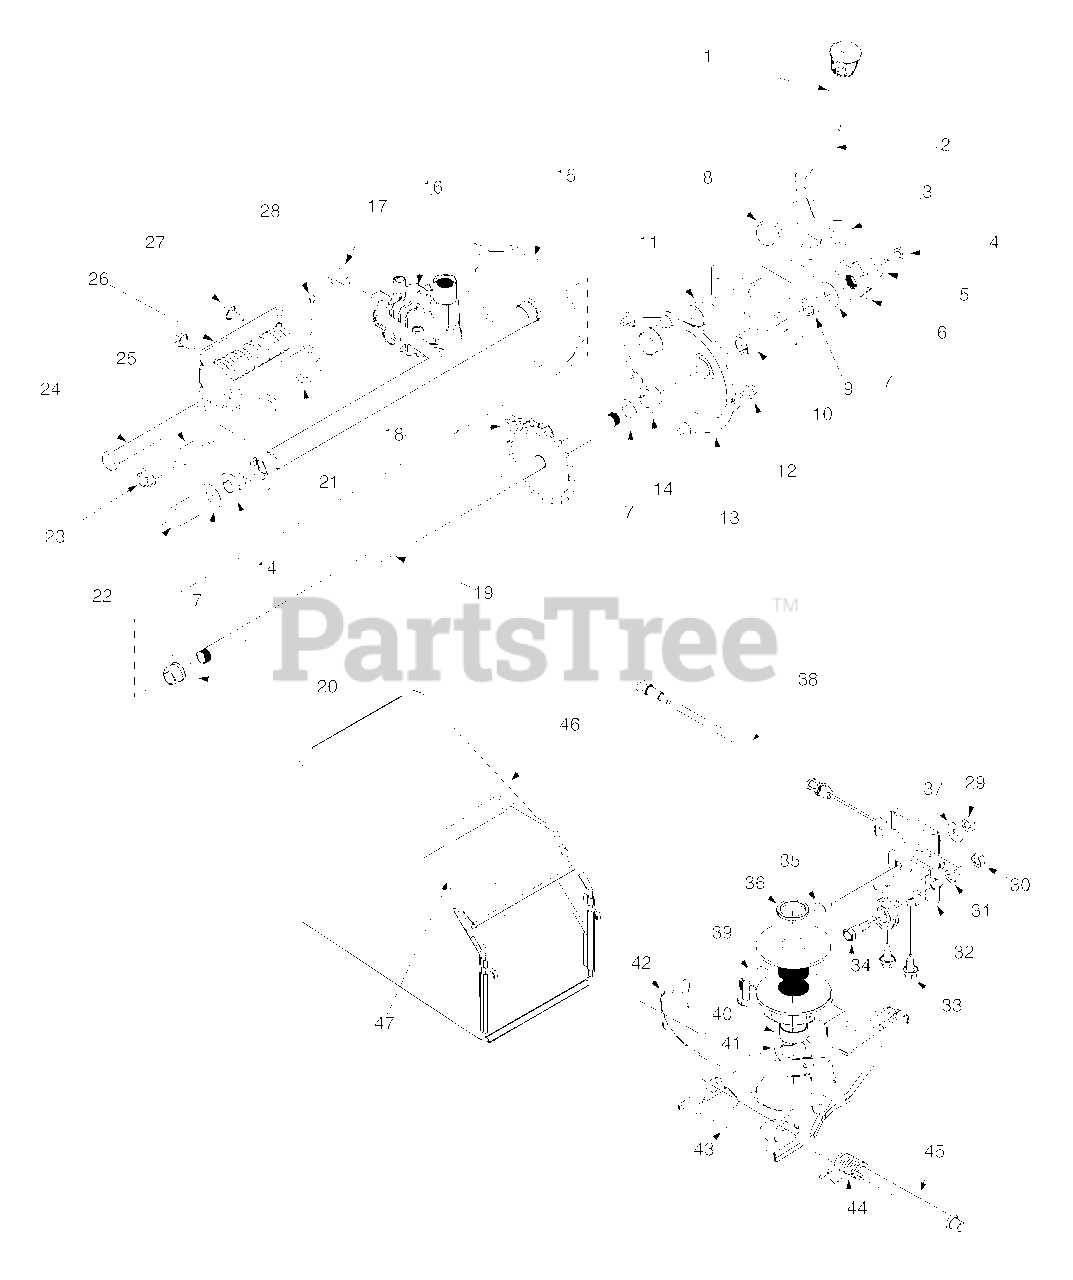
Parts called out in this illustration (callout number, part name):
2	Spring Lever
3	Shoulder Nut .825 x .165 Lg.
4	Cap Screw 1/4-20 x .620
5	Bell Washer .285 ID x .75 OD
6	Wheel Rachet
7	Flat Washer .508 ID x 1.0 OD
9	Spacer .510 ID x .70 OD
10	Sleeve Bearing .504 ID x .830 OD
11	Shoulder
12	Tap Screw 1/4-20 x .375
16	Transmission Assembly Complete
17	Hex Screw 5/16-18
18	Chain
19	Rear Axle Assembly
20	Flange Bearing .506 ID x .715 Lg
21	Torsion Spring
22	Spacer .550 ID x .750 OD
23	Screw 3/8-16 x .25
24	Clevis Pin .50 Dia x 4.82 Lg.
25	Spacer .385 ID x .624 OD
28	Cotter Pin
29	Hex Nut 1/4-20
30	Hex Nut 1/4-28
31	Lock washer 1/4
34	Screw 1/4-20 x .375
35	Screw 1/4-20 x .625
36	Spacer Sleeve 88ID x 1.13 x .12
37	Bell Washer.265 x .75 x .062
38	Cable - 6-Speed (53")
39	Pulley Assembly Complete
40	Spacer Sleeve 88 ID x 1.00 x .48
41	Wave Washer 1.38 OD x .88 ID .029
45	Shaft Pivot 3/8OD x 7.75 LG
46	Grassbag - Black
